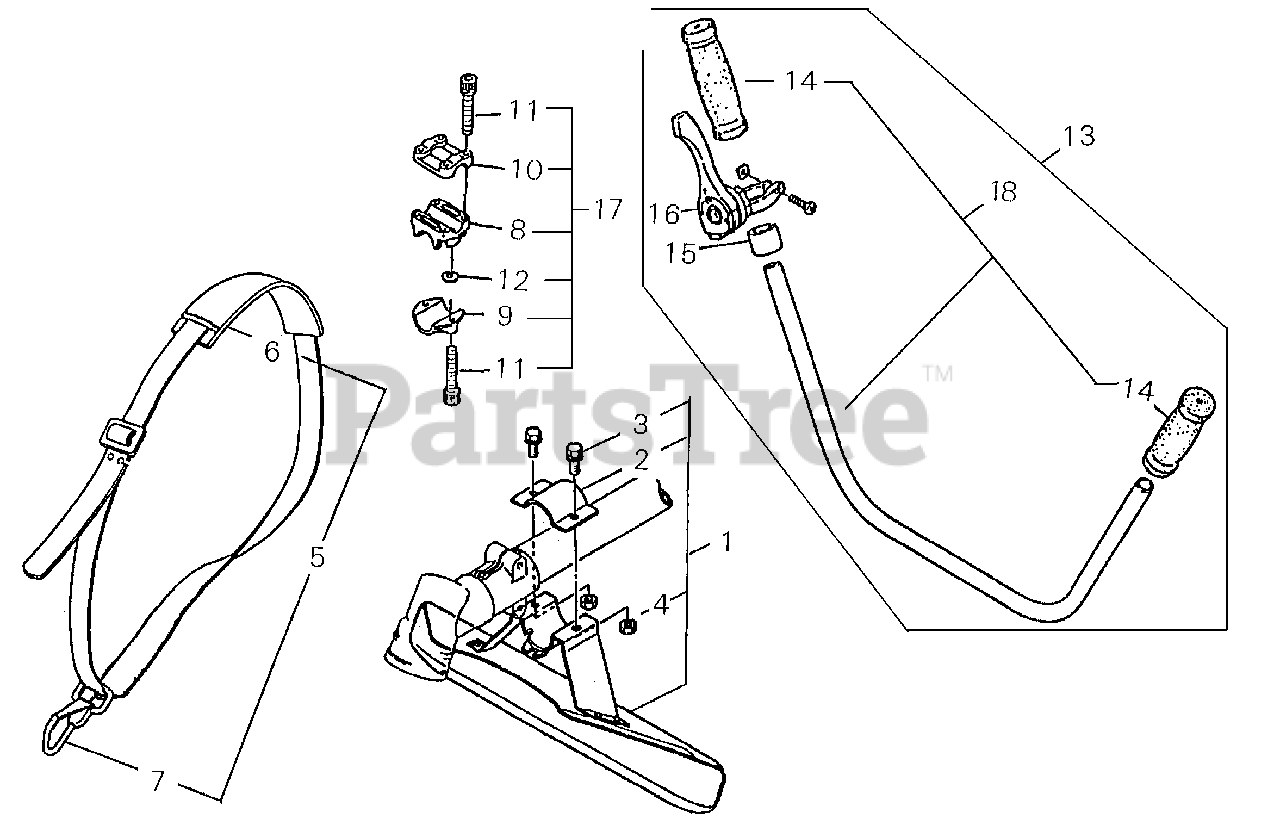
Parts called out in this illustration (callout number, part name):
1	DEBRIS SHIELD KIT
2	GUARD, CLAMP
3	SCREW - 5X12
4	NUT - 5
5	STRAP ASSY
6	PAD, SHOULDER
7	HOOK, SNAP
8	BRACKET, HANDLE
9	CAP - LOWER
10	CAP - UPPER
11	SCREW - 5X25
12	WASHER - 5
13	HANDLE ASSY
14	GRIP
15	COLLAR
16	LEVER, THROTTLE
17	HANDLE BRACKET KIT
18	HANDLE ASSY
